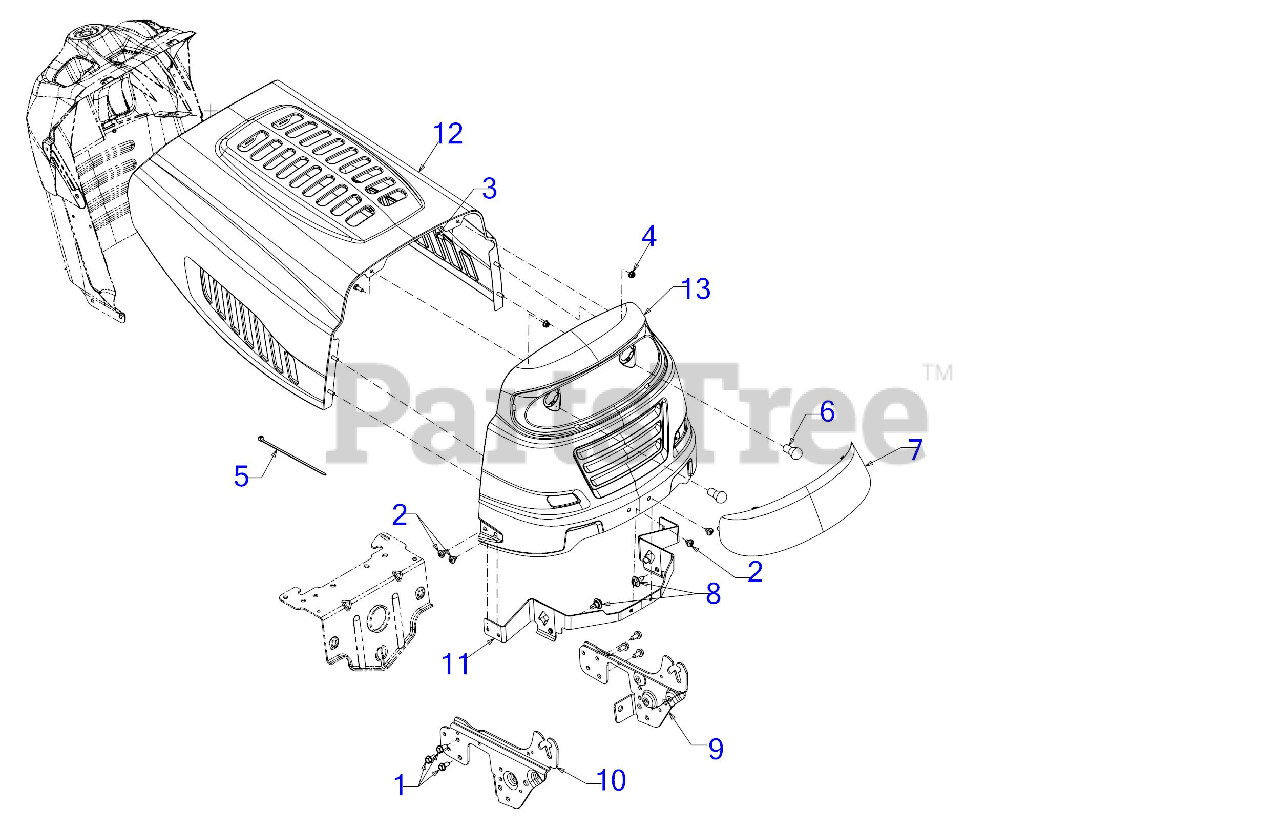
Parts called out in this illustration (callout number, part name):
1	SCREW 5/16-18 x .750
2	SCREW 5/16-18 x .375
3	SCREW 1/4-20 x .620 GR5
4	FLANGE LOCK NUT
5	7" CABLE TIE
6	MINIATUURE BULB 12V
7	GRILL LENS
8	SHOULDER SCREW .43X.29X5/16-18 TT
11	HOOD PIVOT BRACKET
